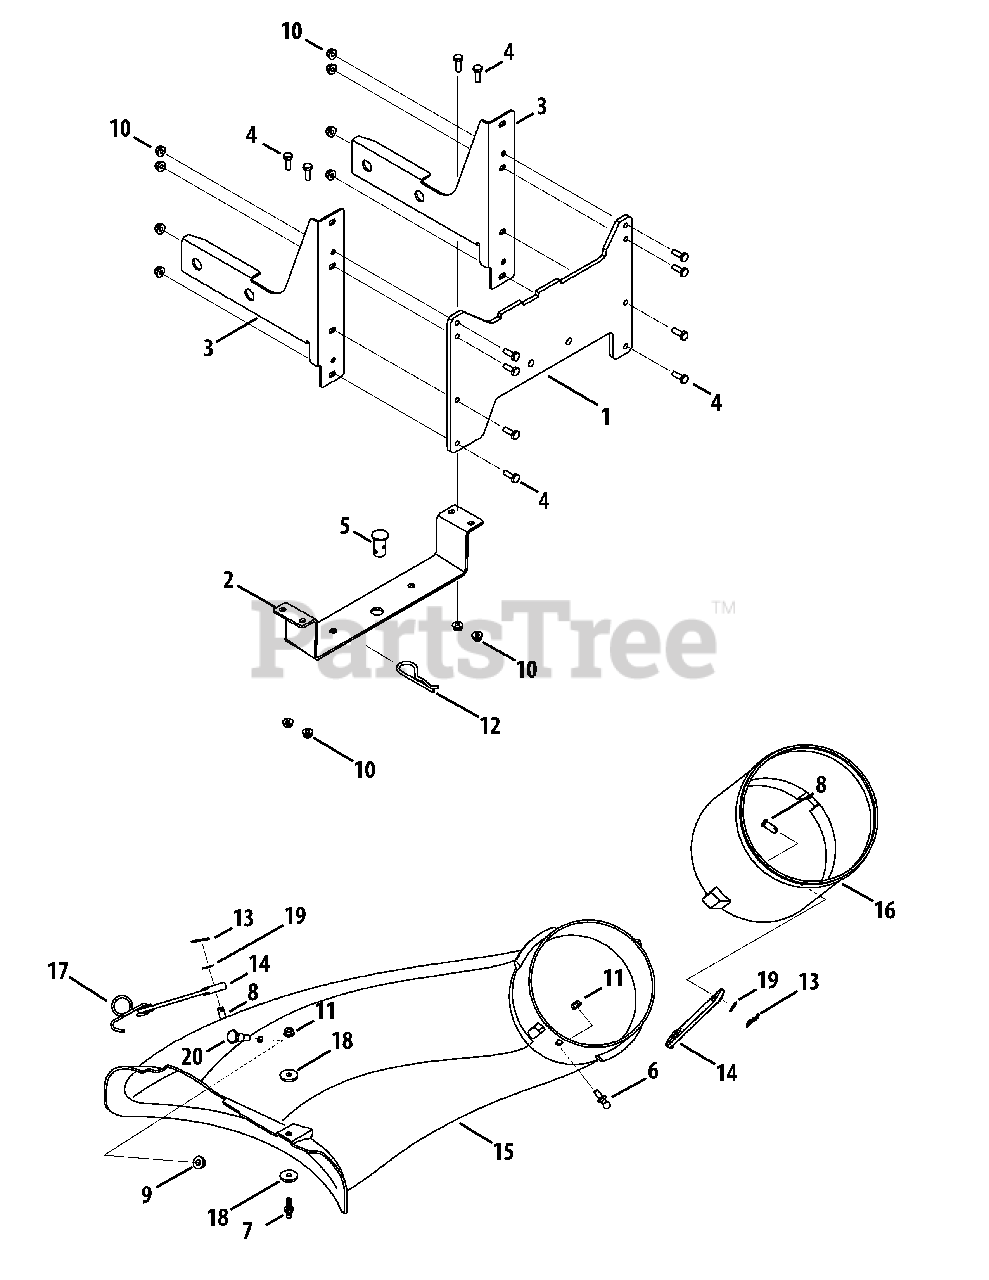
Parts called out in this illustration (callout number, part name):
3	Catcher Support Bracket
4	Hex Head Screw, 1/4-20 x .75
5	Clevis Pin, .62 Dia.
6	Grasscatcher Pin,1/4-20
7	Attachment Pin, 1/4 X 0.66 Lg
8	Clevis Pin, 5/16 x 3/4
9	Flange Lock Nut, 5/16-18
10	Flange Lock Nut, 1/4-20
11	Flange Lock Nut, 1/4-20
12	Internal Cotter Pin, .148 X 3.00
13	Bow-Tie Cotter Pin, .72
14	Chute Strap, 6.00 Lg.
15	Bagger Discharge Chute, 42t
16	Bagger Chute Adaptor, 7x10.5
17	Torsion Spring Hook
18	Flat Washer, .265x.938x.120
19	Flat Washer, .344 X .62 X .033
20	Shoulder Screw, .437 Dia. X .54
